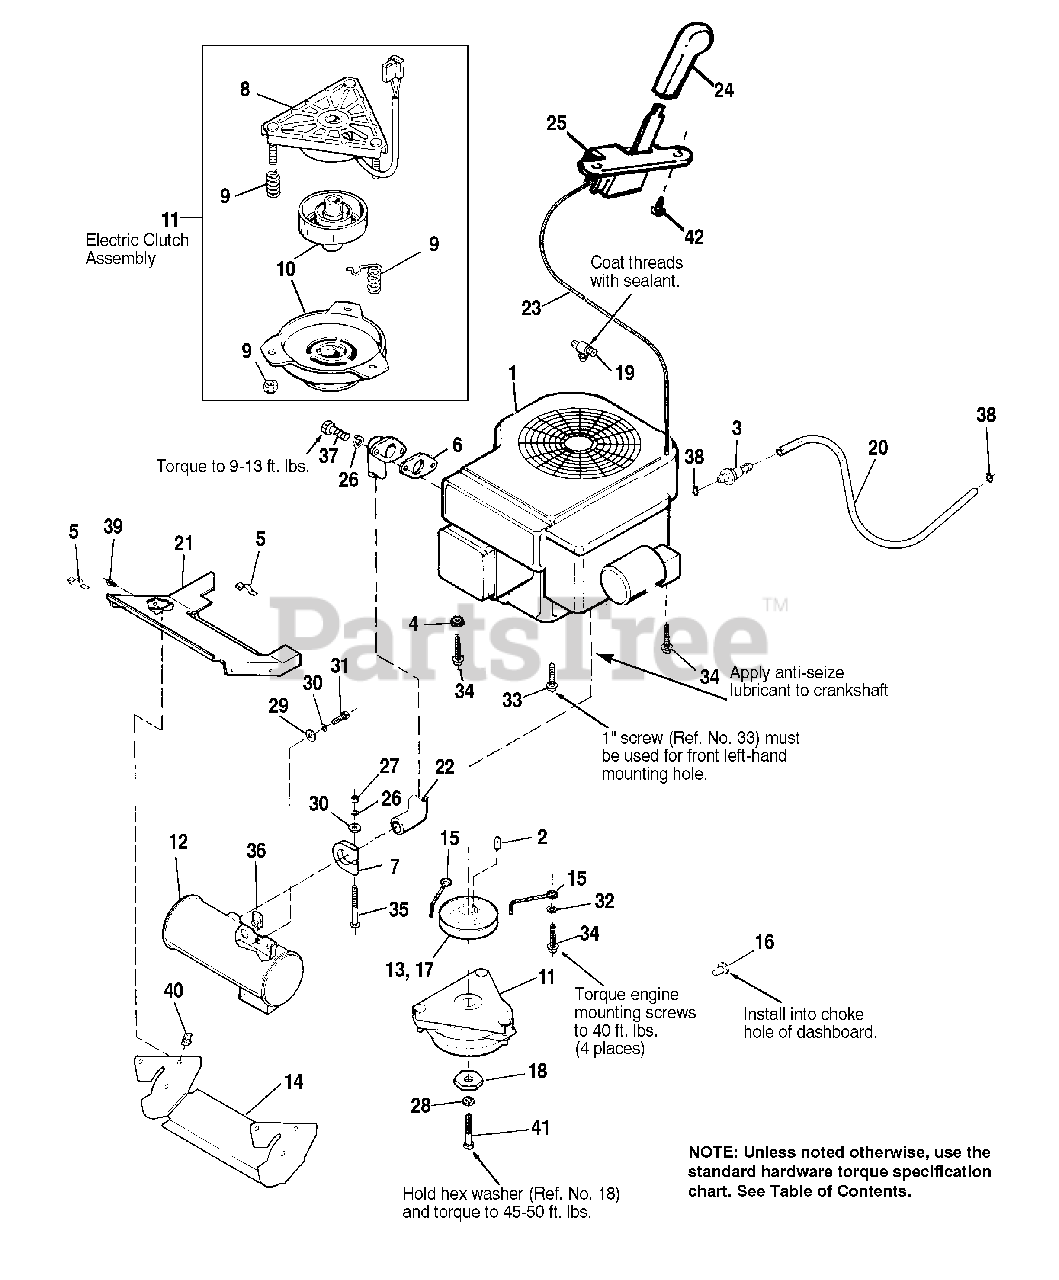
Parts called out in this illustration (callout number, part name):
1	ENGINE, Briggs & Stratton
2	KEY, Hi-Pro
3	FUEL FILTER
4	LOCKWASHER, External Tooth, 3/8
5	CLIP
6	GASKET, Muffler
7	CLAMP, Muffler
8	FIELD ASSY., Clutch
9	SPRING & NUT KIT
10	ROTOR & ARMATURE ASSY.
11	ELECTRIC CLUTCH
12	MUFFLER ASSY.
13	PULLEY ASSY.
14	DUCT, Lower Muffler
16	FASTENER, Panel
17	PULLEY ASSY.
18	WASHER, Hex
19	VALVE, Oil Drain
20	HOSE, Fuel, 38" Long
21	DUCT, Top, Muffler
22	PIPE, Exhaust
23	CABLE, Throttle
24	KNOB, Throttle
25	THROTTLE CONTROL ASSY.
26	LOCKWASHER, 5/16
27	NUT, Hex, Full, 5/16-18
28	LOCKWASHER, 7/16
29	WASHER, Plain, 5/16
30	WASHER, Plain, 5/16
31	CAPSCREW, Hex, 5/16-18 x 1
32	WASHER, Plain, 3/8
33	SCREW, Hex, Washer Hd., Taptite, 3/8-16 x 1
34	SCREW, Hex, Washer Hd., Taptite, 3/8-16 x 1-1/2
35	CARRIAGE BOLT, 5/16-18 x 2-3/4
36	PAL NUT, 5/16-18
37	CAPSCREW, Socket Hd., 5/16-18 x 3/4
38	CLAMP, Hose
39	SCREW, Flange, Whizlock, 1/4-20 x 5/8
40	PAL NUT, 1/4-20
41	CAPSCREW, 7/16-20 x 2-1/2
42	SCREW, Hex, Washer Hd., Plastite, 1/4-20 x 1/2
